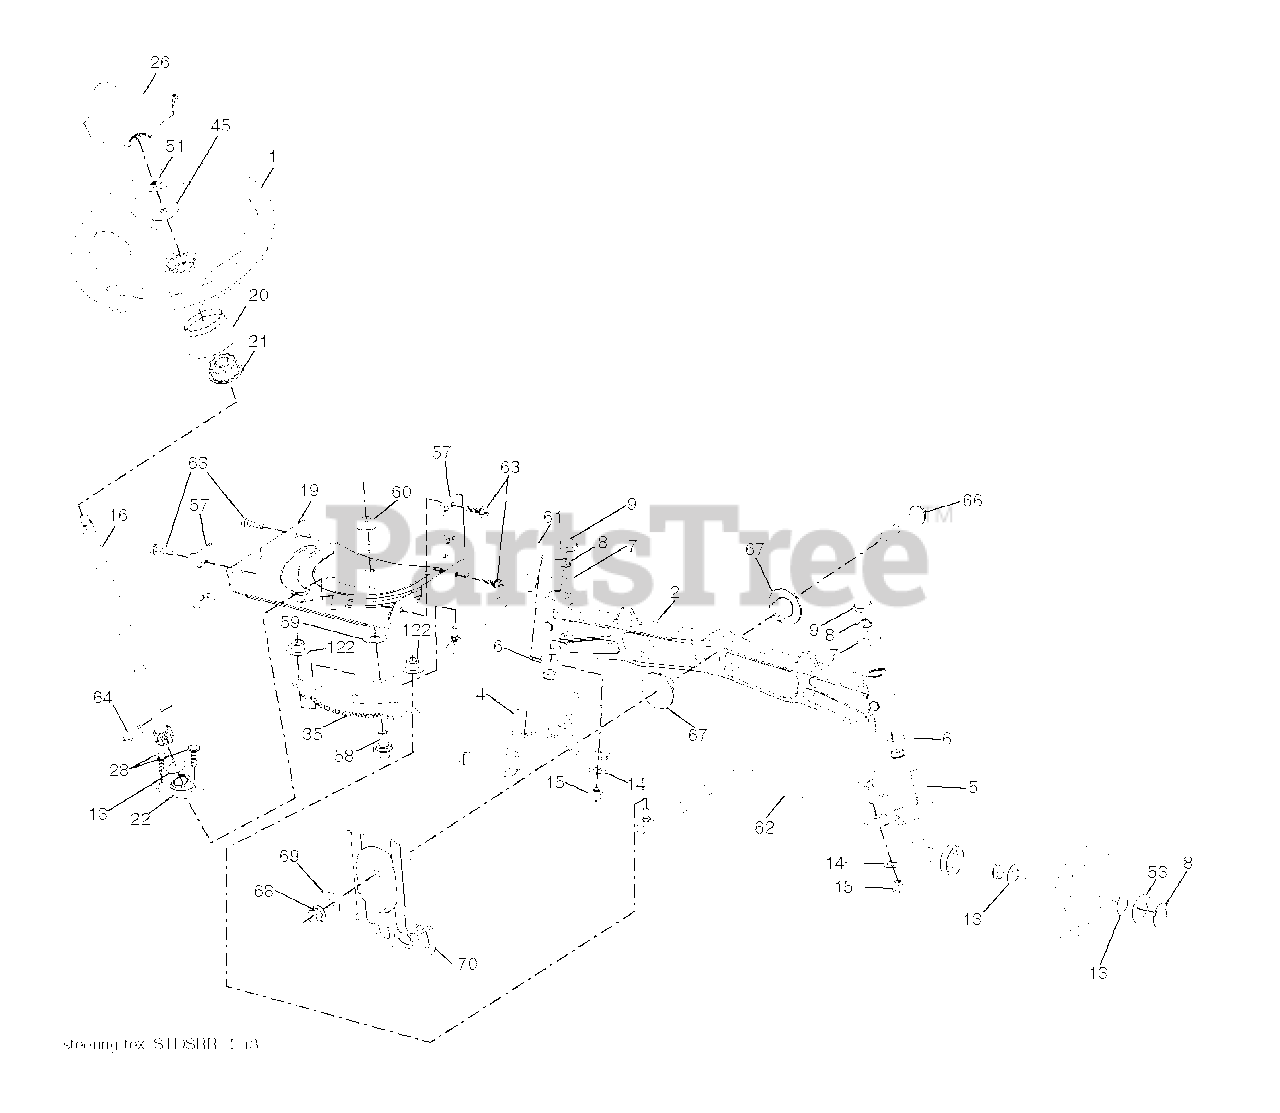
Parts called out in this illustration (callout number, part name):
1	WHEEL.STEERING.MLT.BR.YEL/OVRM
2	AXLE.CAST.IRON
4	SPINDLE.WELDED.LH.15"TEX
5	SPINDLE.WELDED.RH.15"T
8	RING CLIP
9	CAP.SPINDLE.BLACK
14	WASHER, LOCK 3/8
15	NUT CROWNLOCK 3/8-24
16	SHAFT, STEERING
19	PLATE.STEER.DDL.NLT/NG
20	BOOT, STEERING
21	ADAPTER, WHEEL STNG..
22	STEERING.SUPT.LOWER.
26	CAP.WHL.STRNG.MULTI.BRND.YEL
28	SCREW, 3/8-16X3/4
35	GEAR.SECTOR.PLATE.DDL.
45	WASHER 9/16"ID, 2 3/8""OD
51	NUT.HEX.1/2-20
53	WASHER.HARDENED
57	BRACKET.UPSTOP.TEX
58	BOLT.SHOULDER.SECTOR.P
59	WASHER.THURST.SECTOR.S
60	NUT FLANGE LOCK 5/8-11
61	DRAGLINK.LH.BALLSTUD.D
62	DRAGLINK.RH.BALLSTUD.D
63	SCREW
64	RETAINER.CLIP.SPRING.S
66	BOLT HEX FGHD 7/16-14 X 3 SERR
67	BUSHING.PM.FRONT AXLE
68	NUT.LOCK.FLANGE.7/16
69	WASHER.1.5X.505X.118
70	BRKT.DECK.SUSPENSION.F
122	CAP.GEAR.SECTOR.TEX
